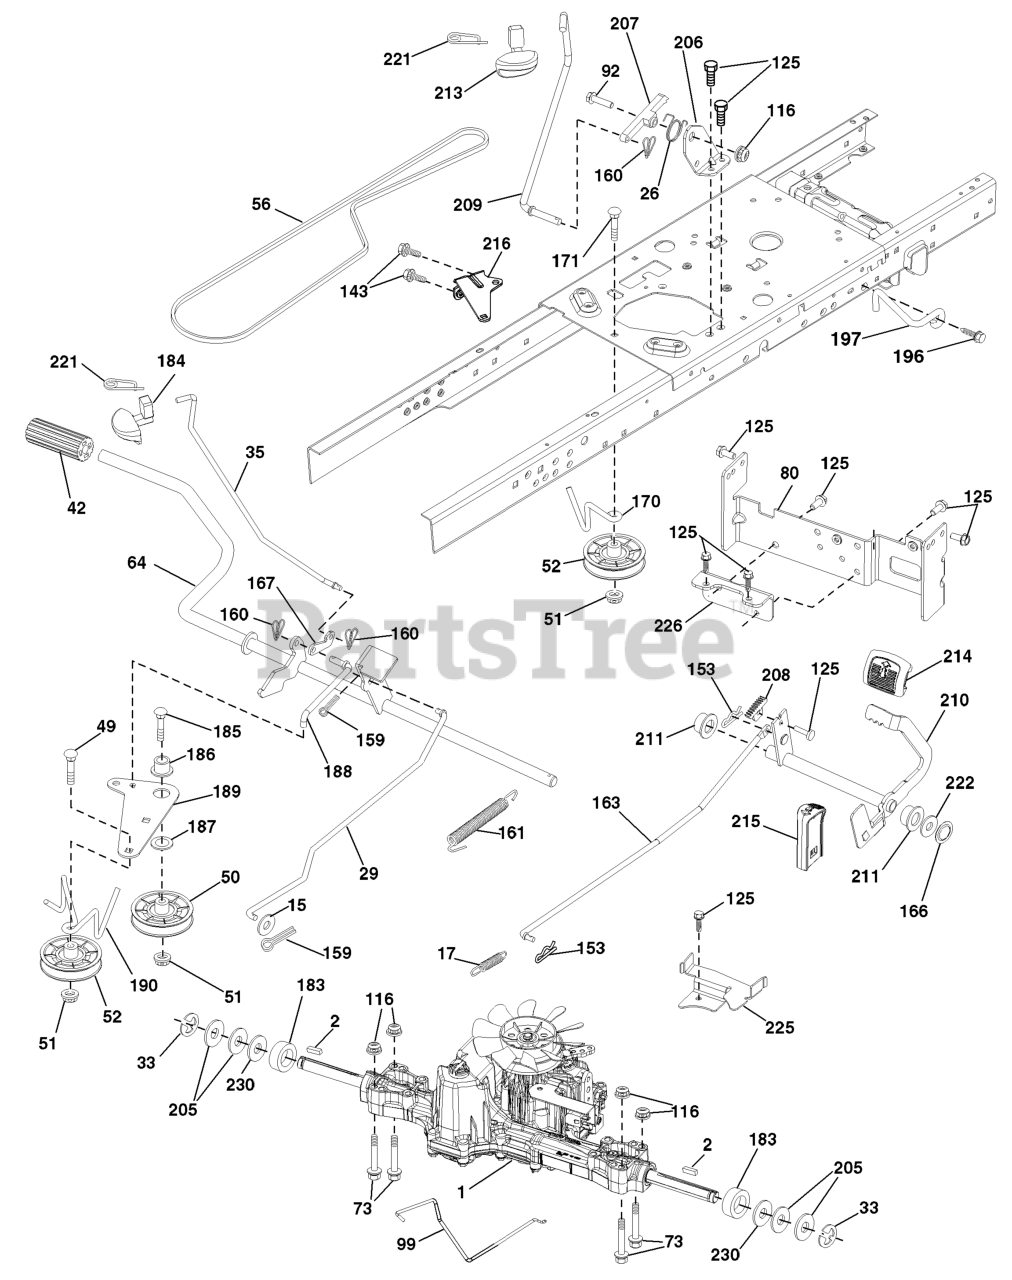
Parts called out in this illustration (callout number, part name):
1	TRANSAXLE, TUFFTORQ K46
2	SQUARE KEY
15	WASHER
17	SPRING.BRAKE.K46.GREEN
26	SPRING.RETURN.CRUISE
29	ROD.BRAKE.K46
35	ROD.BRAKE.PARKING.GT.H
42	PEDAL COVER T
50	IDLER.FLAT.910.OFFSET
51	NUT LOCK FLG 3/8-16 UNC
52	IDLER.V-GROOVE.910.OFFSET
56	V-BELT.MOWER.92.40.42/K46
64	SHAFT.ASM.PEDAL.BRK.CNTR
73	BOLT HEX 5/16-18 GR 5
80	STRAP TORQUE
92	BOLT
99	ROD.SPRING.BYPASS.K46.LT.Z
116	NUT LOCK HEX FLANGE 5/16-18
125	SCREW
143	Screw 5/16-18 x 1/2
153	RETAINER M
159	COTTER PIN
160	RETAINER CLIP
161	Spring, Return, Clutch
163	ROD.CONTROL.PEDAL.K46
166	NUT.PUSH.625.2006
167	LATCH.BRAKE.SPRING
170	KEEPER.V-IDLER.CENTER.
171	BOLT
183	SPACER AXLE
184	HANDLE.PARKG.BRK.HUSQ X667
185	BOLT
186	SPACER.RETAINER
187	WASHER 12/32X2X10GA
188	RP.LINK.CLUTCH.GROUND.DRIVE
189	BELLCRANK.GROUND.DRIVE.TEX.
190	KEEPER.BELLCRANK.DRIVE
196	SCREW 3/8-16X1
197	LINK.CLUTCH.ANIT-ROTAT
206	BRKT.MOUNT.LATCH.CRUIS
207	LATCH.CONTROL.CRUISE
208	GEAR.SECTOR.CONTROL.CR
209	ROD.CONTROL.CRUISE.GT.
210	ROCKER.ASM.PEDAL.CONTR
211	BEARING.NYLON
213	KNOB.CONTROL.CRUSIE.HU
214	PEDAL.FORWARD.HUSQVARNA.DEALER
215	PEDAL.REVERSE.TEX.GT.4
216	BRACKET.PULLEY.IDLER.W/TEX
221	RETAINER.SPRING.CLIP.H
222	WASHER 21/32 X 1-1/4 X 10 GA.
225	KEEPER.BELT.TRANSAXLE.K46
226	BRACKET.MOUNT.TORQUE.K46.TLT
230	WASHER.HARDENED
